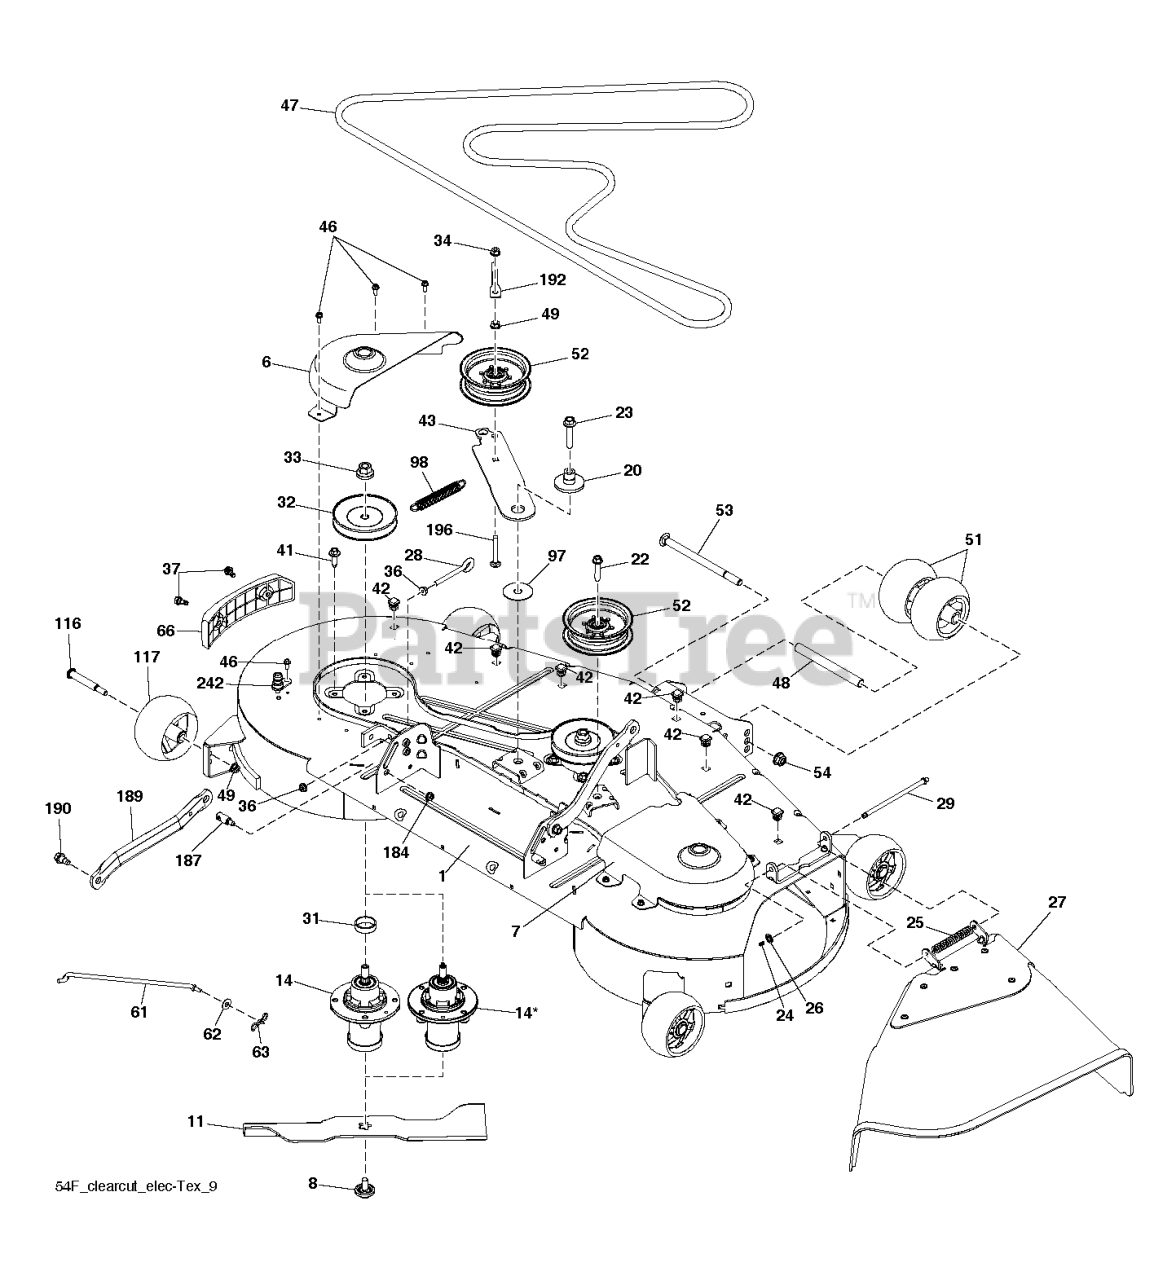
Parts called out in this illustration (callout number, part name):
1	SERVICE KIT KIT.SVC.WELDMENT.5
6	COVER 54 CLEARCUT, LH MANDREL,
7	COVER 54 CLEARCUT RH MANDREL G
8	BOLT.WASHER.ASM.7/16-2
11	BLADE CC54 PZ STYLE HI LIFT BL
14	MANDREL.DECK.ASSEMBLY
20	SPACER.IDLER.PULLY.HUB
22	BOLT;HEX_3/8-16 X 1.78.CLRZINC
23	SCREW.7/16-14 X 2.125.WASHER
24	CAP-SLEEVE LT
25	SPRING.42.FCS.DEFLECTOR
26	NUT PUSH M
27	DEFLECTOR ASSY 54 CLEARCUT RES
28	GSPW Bolts
31	WASHER.SPACER.MANDREL
32	PULLEY/MANDREL
36	GSPW Hardware
37	SHOULDER BOLT 5/16-18TT
41	BOLT.HEX.WASHR.HED.313-18X1.19
43	ARM IDLER ARM, CLEARCUT 54 BLA
46	SCREW.1/4-20X5/8
47	BELT CLEARCUT 54, TRACTOR DECK
49	NUT LOCK FLG 3/8-16 UNC
51	ROLLER, GAUGE .635 BORN
52	PULLEY.IDLER.2006
54	NUT 1/2-13 HEX FLANGE NYLOK CL
63	PIN.COTTER.5/16.BOW TI
66	BUMPER ASSY 54 CLEARCUT TRIM S
98	SPRING.EXTN.42.FCS.TR.DECK.DRV
117	WHEEL.GAUGE.RALLY
187	STUD.W/"D"ANTI-ROTATION
189	ARM.RFIXED.MOWER.SUSPNSIONX431
190	BOLT.SHOULDER
192	KEEPER.BELT.IDLER.54"T
242	PORT.WASHOUT
